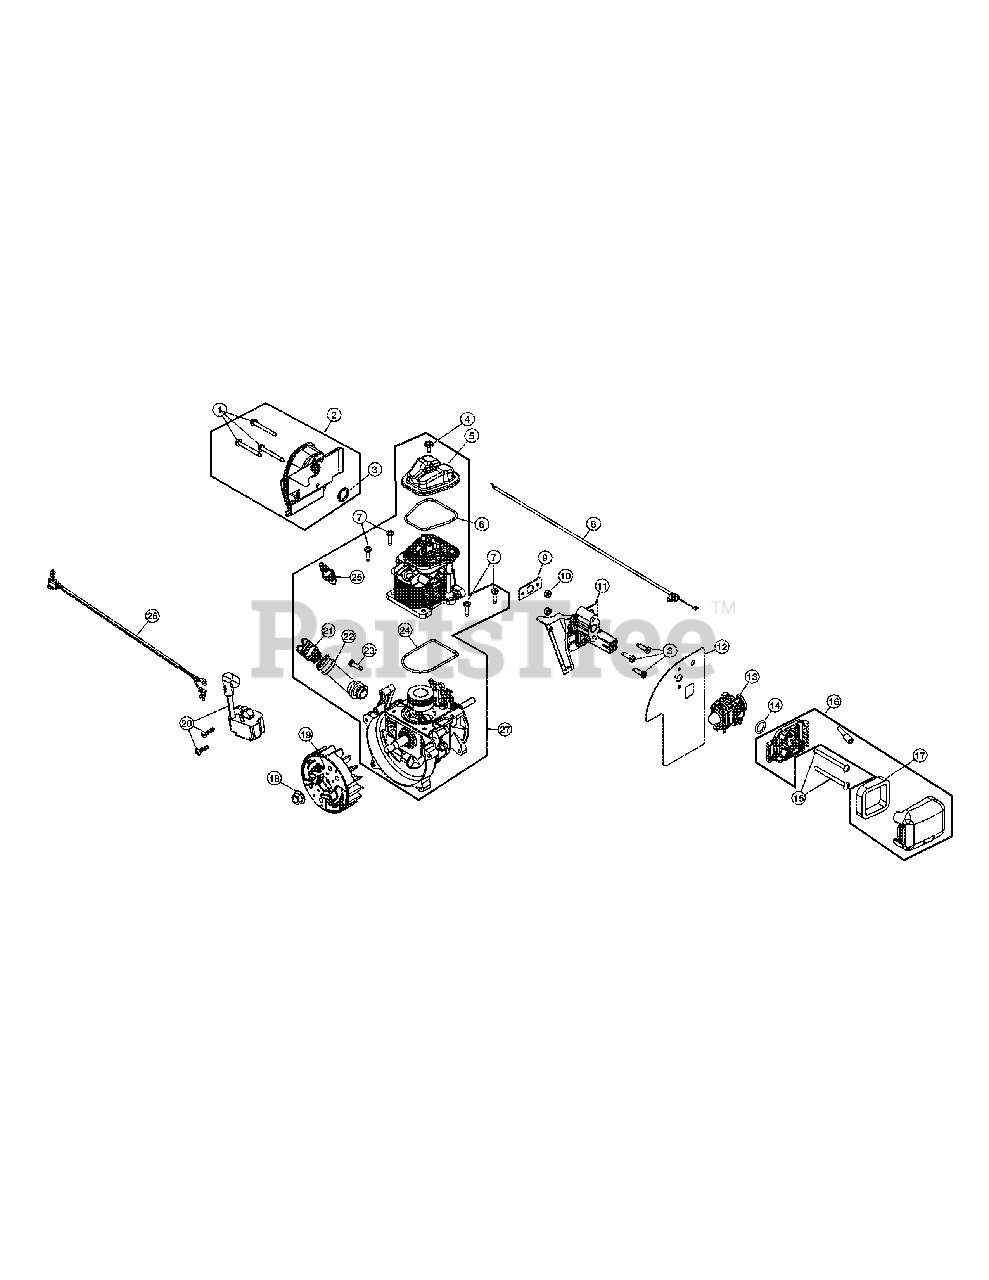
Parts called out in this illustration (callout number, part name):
1	Muffler Screws
2	Muffler Assembly
3	Muffler Gasket
5	Rocker Cover
6	O-Ring
7	Screw
8	Throttle Cable
9	Insulator Gasket
11	Insulator
12	Carburetor Gasket
13	Carburetor
14	Carburetor O-Ring
16	Air Cleaner Assembly
17	Air Filter
19	Flywheel Assembly
20	Module
21	Oil Plug
22	Oil Fill Tube
24	O-Ring
25	Spark Plug
26	Lead Wire
27	Shortblock Assembly
